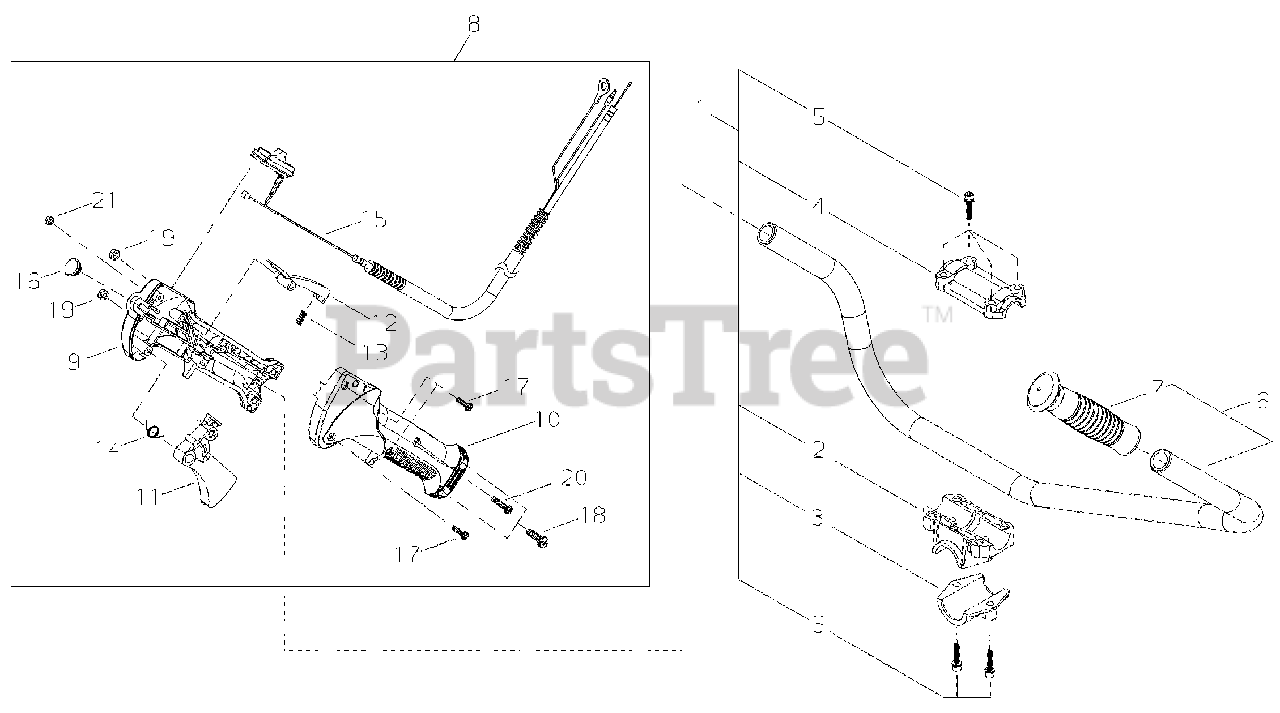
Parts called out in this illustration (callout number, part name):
1	BRACKET KIT, HANDLEBAR
2	BRACKET, LOWER HANDLEBAR
3	BRACKET, MOUNTING
4	BRACKET, UPPER HANDLEBAR
5	BOLT M5×25
6	HANDLEBAR ASSY
7	GRIP
8	THROTTLE CONTROL ASSY
9	CONTROL HANDLE - RIGHT
10	CONTROL HANDLE - LEFT
11	TRIGGER, THROTTLE
12	LOCKOUT, THROTTLE
13	SPRING, COMPRESSION
14	SPRING, TORSION
15	CABLE ASSY, CONTROL
16	PLUG, RUBBER
17	SCREW, TAPPING 4×16
18	SCREW M5×20
19	NUT M5
20	SCREW M4×23
21	NUT M4
